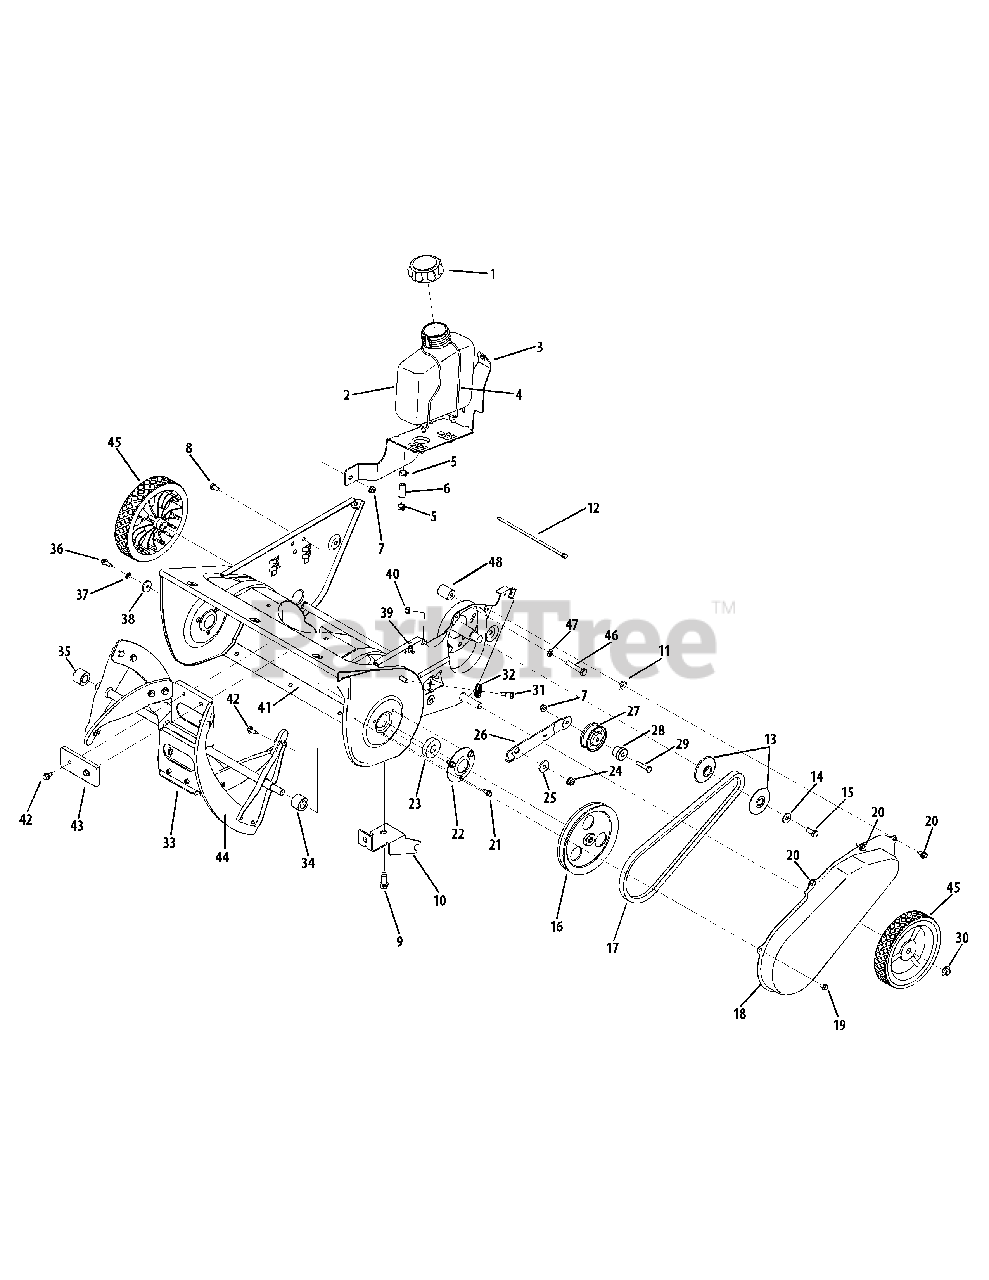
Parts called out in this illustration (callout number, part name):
1	Fuel Cap
2	Fuel Tank, 2 Qt.
3	Fuel Tank Bracket
4	Fuel Tank Support Wire
5	Hose Clamp, .490
6	Fuel Line Hose
7	Flange Lock Nut, 1.4-20
8	Hex Bolt, 1.4-20 x .620
9	Screw, 3.8-16 x 1.000
10	Engine Bracket
11	Push Nut, .25 ID x .50 OD
12	Cable Tie, 7.5h
13	Pulley Half, .625 ID x .225 OD
14	Bell Washer, .340 x .872 x .060
15	Hex Bolt, 5.16-24 x .750
16	Pulley, 1.2 x 6.00
17	V-Belt
18	Belt Cover - Red
18	Belt Cover - Green
19	Hex Screw, 1.4-20 x .375
20	Hex Screw, 1.4-14 x .625
21	Hex Screw, 1.4-14 x .500
22	Bearing Cup
23	Ball Bearing, .625 x 37 x 12
24	Flange Lock Nut, 5.16-18
25	Shoulder Spacer
26	Idler Bracket
27	Idler Pulley Assembly, 1.917
28	Shoulder Spacer, .280 x .785 x .538
29	Hex Screw, 1.4-20 x 1.25
30	Push Cap, 1.2
31	Shoulder Screw,
32	Cable Roller
33	Auger Assembly, 21 inch
34	LH Spacer
35	RH Spacer
36	Hex Screw, 1.4-20 x .750
37	Lock Washer, 1.4
38	Flat Washer, .265 x .938 x .120
39	Extension Spring, .33 x 1.12
40	Hex Lock Nut, 1.4-28
41	Auger Housing Assembly, 21 - Red
41	Auger Housing Assembly, 21 - Green
42	Hex Screw, 1.4-14 x .625
43	Rubber Pad
44	Spiral Crescent
45	Wheel, 7 x 1.61
46	Hex Bolt, 5.16-24 x 1.75
47	Lock Washer, 5.16
48	Spacer, .875 x .320 x1.027
